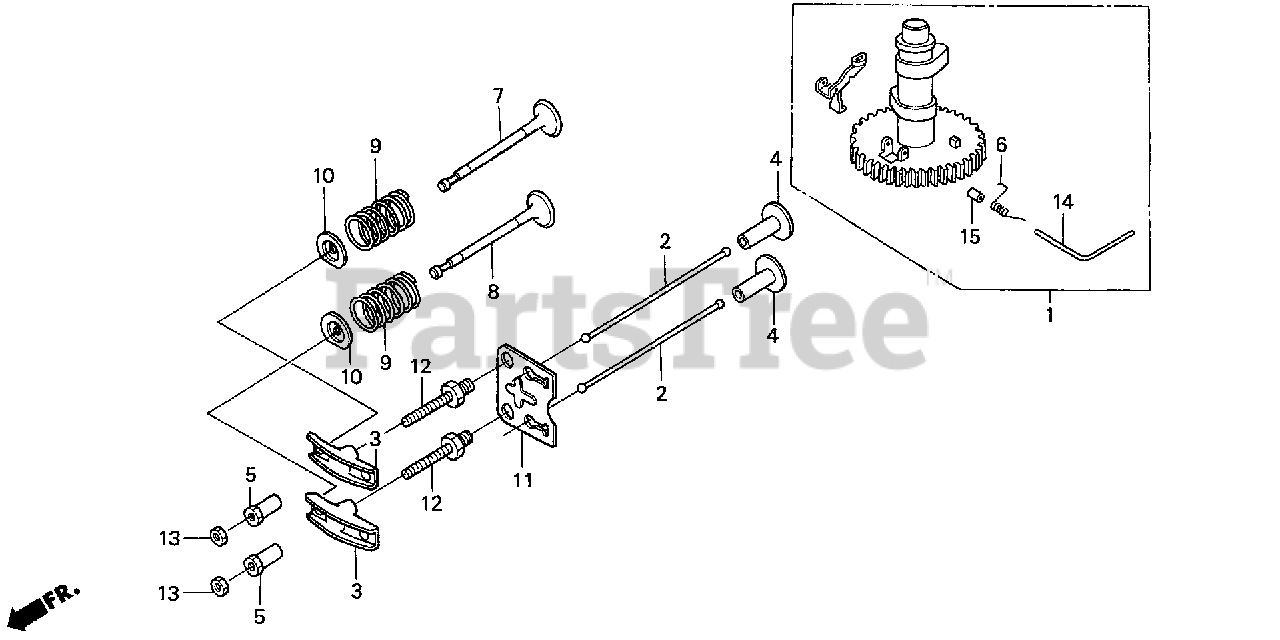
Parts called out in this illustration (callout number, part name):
1	CAMSHAFT ASSY.
3	ARM, VALVE ROCKER
4	LIFTER, VALVE
5	PIVOT, ROCKER ARM
6	SPRING, WEIGHT RETURN
7	VALVE, IN.
8	VALVE, EX.
9	SPRING, VALVE
10	RETAINER, IN. VALVE SPRING
11	PLATE, PUSH ROD GUIDE
12	BOLT, PIVOT (8MM)
13	NUT, PIVOT ADJUSTING
14	PIN, WEIGHT CENTER
15	COLLAR, WEIGHT CENTER
